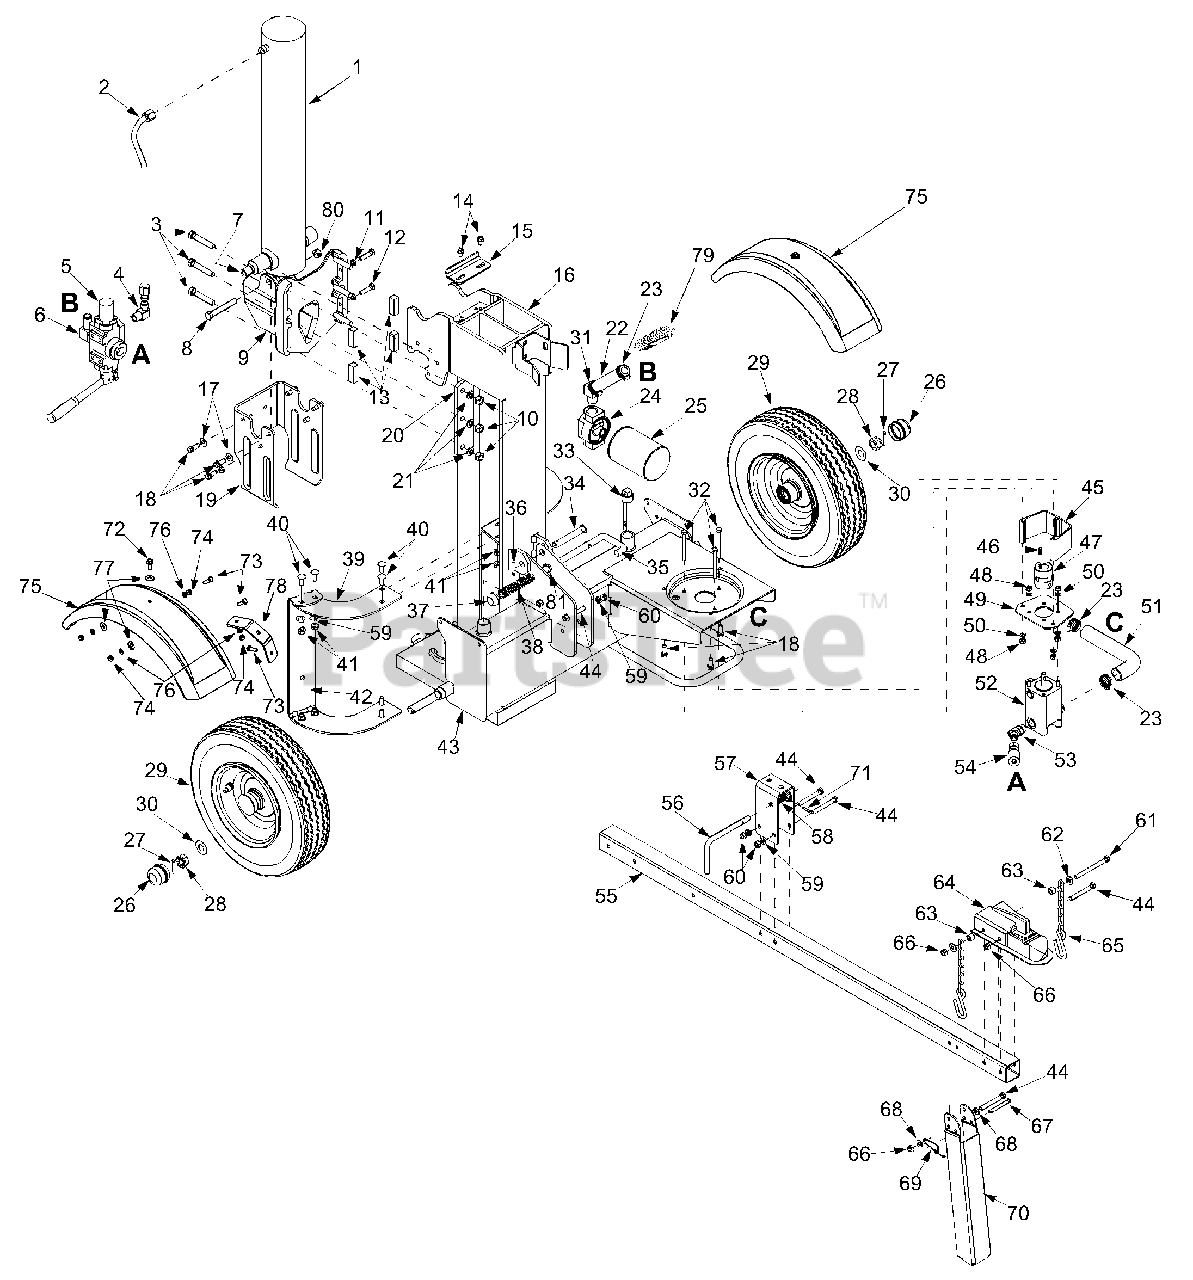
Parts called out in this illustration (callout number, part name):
1	Hydraulic Cylinder
2	Hydraulic Tube
3	Hex Cap Screw 1/2-20 x 2.75
4	90 Degree Solid Adapter
6	Return Elbow
7	Nipple Pipe 1/2-14
8	Hex Cap Screw 1/2-13 x 3.25
9	Wedge Assembly
10	Lock Nut 1/2-20
11	Hex Jam Nut 3/8-24
12	Hex Cap Screw 3/8-24 x 1.5
14	LD Screw 5/16-18 x.75
17	Flat Washer.406 ID x.875 OD
18	Hex Washer Screw 3/8-16 x 1
21	Lock Washer 1/2
22	Return Hose 3/4" ID x 44" Lg.
23	Hose Clamp 5/8"
24	Filter Housing
25	Oil Filter
26	Hub Cap
27	Cotter Pin
28	Slotted Nut 3/4-16
29	Wheel Assembly
30	Flat Washer .760 ID x.500 OD
31	Adapter 3/4-14
32	Hex Screw 5/16-24 x 3.25
33	Vented Dipstick
34	Clevis Pin
35	Lock Rod
36	Cotter Pin
37	Push Cap
38	Compression Spring
41	Hex Nut 3/8-16
43	Frame Assembly
44	Hex Bolt 3/8-16 x 3"
45	Coupling Shield
46	Square Key 3/16" x.75
47	Flexible Coupling .750 x .500
47	Flexible Coupling .875 x .500
47	Flexible Coupling .875 x .437
48	Hex Nut 5/16-24
50	Lock Washer 5/16" ID
52	Gear Pump (11 gpm)
52	Pump Kit
52	Gear Pump (9.5 gpm)
53	45 Degree Elbow
54	High Pressure Hydraulic Hose
56	Latch Rod
58	Spring Compression
59	L-Washer 3/8"
60	Hex Nut 3/8-16
61	Hex Cap Screw 3/8-16 x 4.25
62	Flat Washer.385 ID x.870 OD
63	Spacer.375 ID x.625 OD
64	Coupling Hitch
65	Chain
66	Hex Lock Nut 3/8-16
67	Clevis Pin
68	Flat Washer.375 ID x.738 OD
69	Spring Pin
72	Hex Bolt 5/16-18 x 0.875"
73	Hex Bolt 5/16-18 x 0.875"
74	Hex Nut 5/16-18
75	Black Fender
76	Lock Washer
77	Flat Washer
79	Hose Guard
80	Hex Lock Nut 1/2-13
81	Flat Washer.635 x.93 x.06
